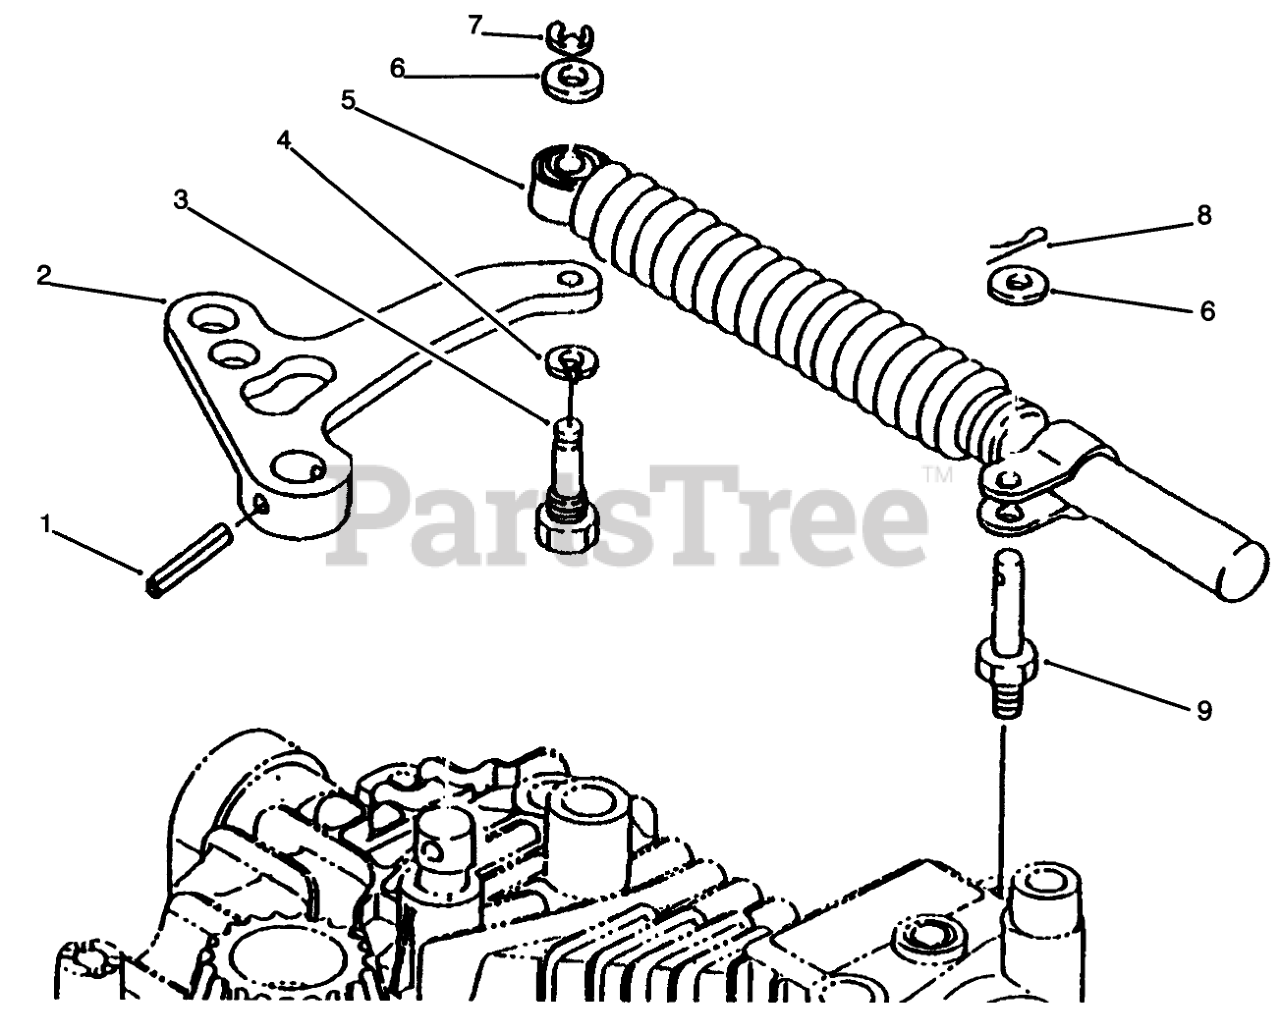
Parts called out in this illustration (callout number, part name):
1	Pin-Roll (Only On: 72043, 72063, 72103)
2	Arm (Only On: 72043, 72063, 72103)
3	Bolt (Only On: 72043, 72063, 72103)
4	Washer (Only On: 72043, 72063, 72103)
5	Shock Absorber (Only On: 72043, 72063, 72103)
6	Washer (Only On: 72043, 72063, 72103)
7	Ring (Only On: 72043, 72063, 72103)
8	Pin-Cotter (Only On: 72043, 72063, 72103)
9	Stud (Only On: 72043, 72063, 72103)
